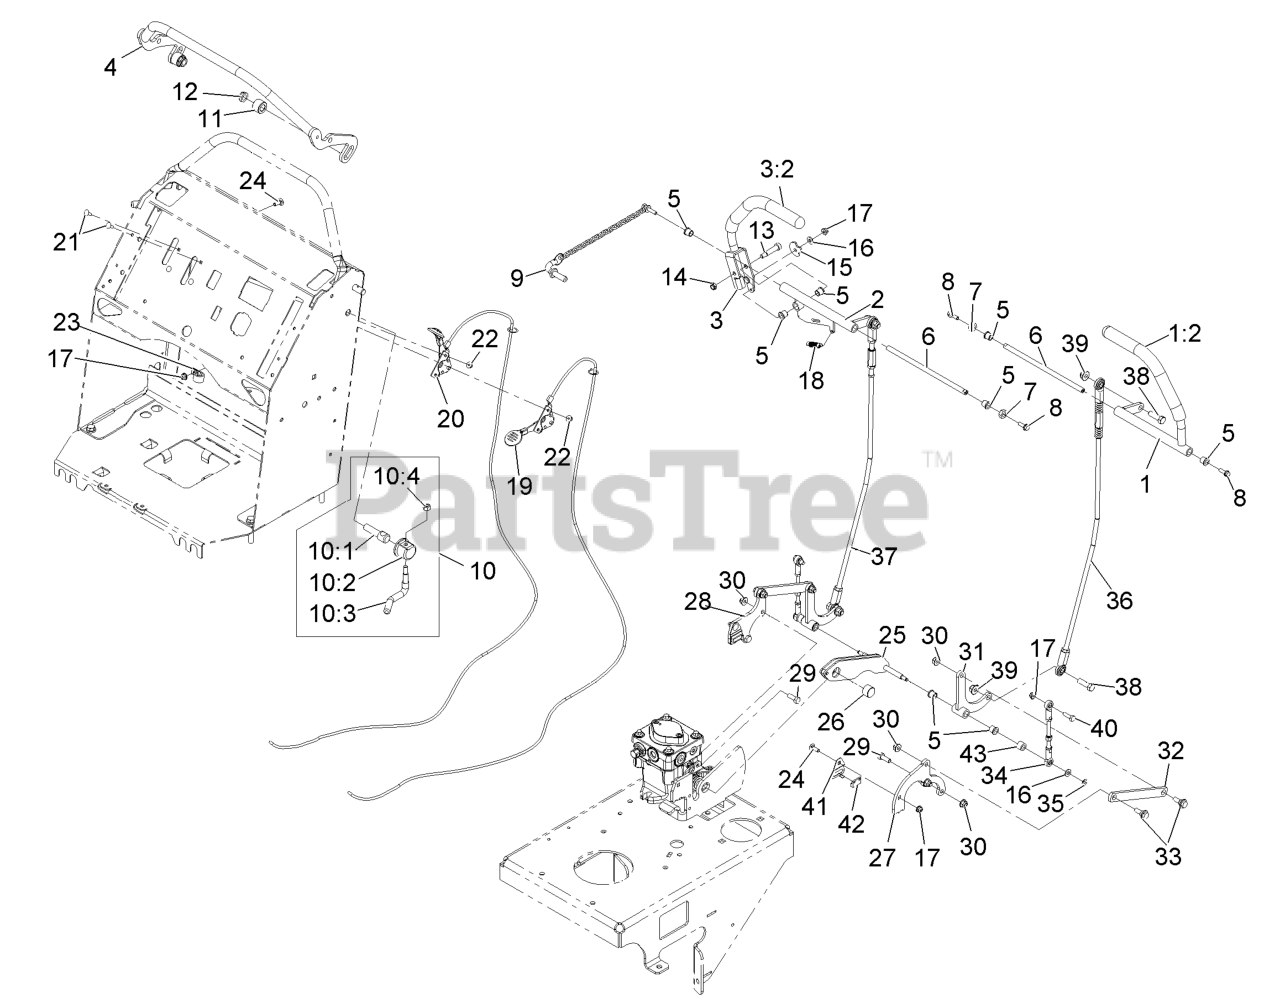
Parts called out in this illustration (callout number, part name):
1	LEVER ASM, LH
1:2	GRIP-HANDLE, CONTROL
2	MOTION CONTROL ASM, LH
3	LEVER ASM, RH
3:2	GRIP-HANDLE, CONTROL
4	TUBE ASM, FRONT SPEED CONTROL
5	BEARING
6	SHAFT-PIVOT, MOTION CONTR
7	SPACER-SHAFT, DRIVE LEVER
8	SCREW-HHF
9	HOC PIN ASM
10	LEVER ASM
10:1	SCREW-LOCK
10:2	CAP-LOCK
10:4	NUT-LOCK, NI
11	SPACER-CLAMP
12	NUT-HEX
13	SCREW-HSH
14	NUT-LOCK, NI
15	CAM-LEVER
16	WASHER-FLAT
18	SPRING-EXTENSION
19	CONTROL-THROTTLE
20	CONTROL-CHOKE
21	BOLT-CARR
23	CLAMP-CABLE
24	BOLT-CARR
25	BELLCRANK LINK ASM
26	PIN-BELLCRANK LINK RETAIN
27	ARM-PUMP CONTROL
28	ARM, PUMP CONTROL RH
29	SCREW-HH
30	NUT-HF, NI
31	BELLCRANK-LOWER
32	LINK-BELLCRANK, PUMP
33	SCREW-SHOULDER
34	VERTICAL ADJUST LINK
36	LINKAGE-TRACKING CONTROL,
37	LINKAGE-TRACKING CONTROL,
38	SCREW-HH
39	NUT-HF, NI
40	SCREW-HH
41	CLAMP-SWITCH
42	ACTUATOR-SWITCH, REED
43	SPACER-WHEEL
